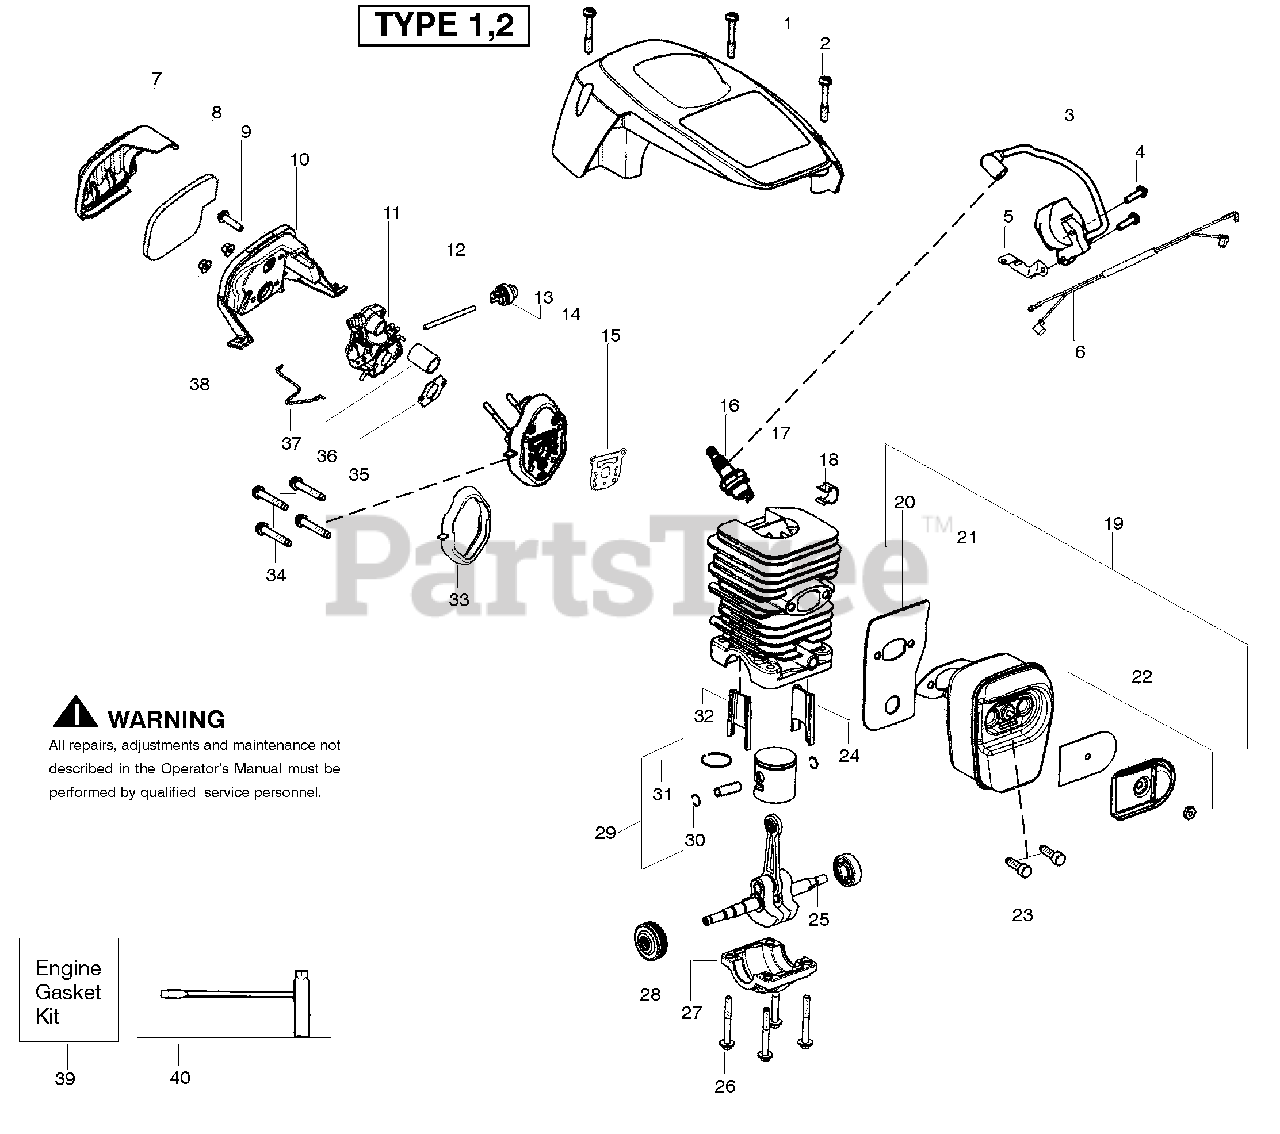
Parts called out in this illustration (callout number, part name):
1	Shield-Cylinder
3	Module-Ignition
5	Strap-Ground
6	Assy-Wire Harness
7	Cover-Air Filter
8	Filter-Air
10	Housing-Air Filter
11	Carburetor Zama W-26
12	Kit-Fuel Line (Small)
13	Bulb-Purge "snap-in"
14	Kit-Carb. Adaptor
15	Gasket-cyl. o-ring (kit)
16	Accy-Spark Plug (RCJ-7Y)
17	Kit-Cylinder
18	Clip-High Tension Lead
19	Kit-Muffler
20	Backplate-Muffler
21	Gasket-Muffler (kit)
22	Kit-Spark Arrestor
23	Bolt-Muffler
24	Insert-Left (black) Cyl.
25	Assy-Crankshaft/Rod
27	Cap-Crankcase
28	Assy-Bearing/Seal
29	Kit-Piston
30	Retainer-Piston Pin
31	Ring-Piston
32	Insert-Right (gray) Cyl.
33	Seal-Adaptor (kit)
35	Gasket-Carb. (kit)
36	Tube-Intake
37	Wire-Throttle
38	Nut-Carb.
39	Kit-Gasket
40	Scrench
